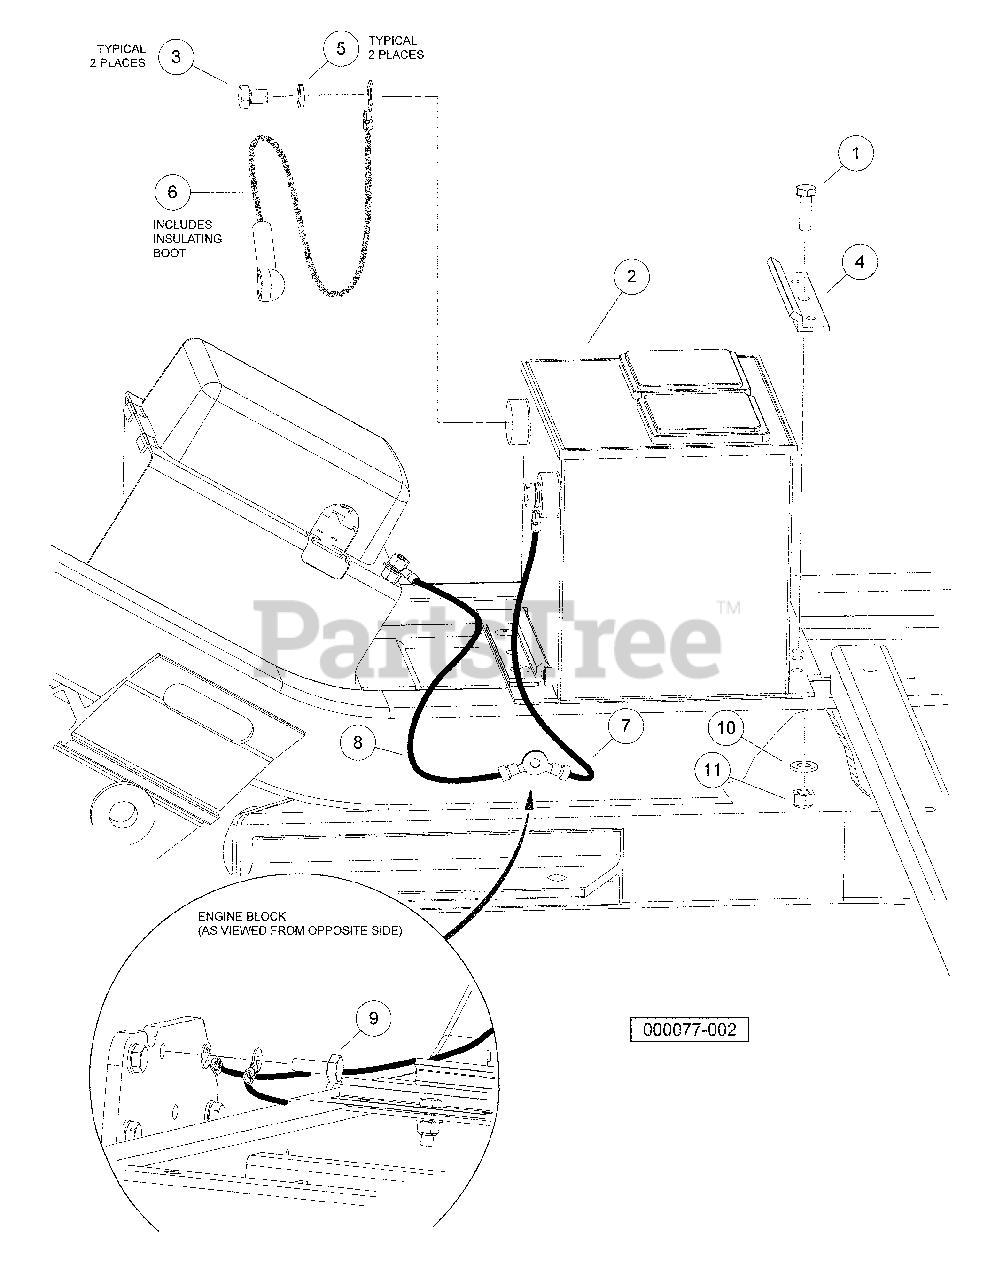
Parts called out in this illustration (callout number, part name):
1	Screw, 5/16-18 X 1.00 Hex Cap
2	Battery, 12-Volt
3	Screw, 3/8-16 X 0.50 Stainless Steel Hex-Head
4	Clamp, Battery
5	Lockwasher, 3/8 Stainless Stl
6	Asm, #6 Red Wire
7	Wire Asm, #6 Blk, Awd, 350
8	Wire Asm, #6 Blk, Awd, 325
9	Bolt, M10 X 1.25 X 25 Loctite
10	Washer, 5/16 Type A Flat
11	Locknut, 5/16-18 Nylon Insert
